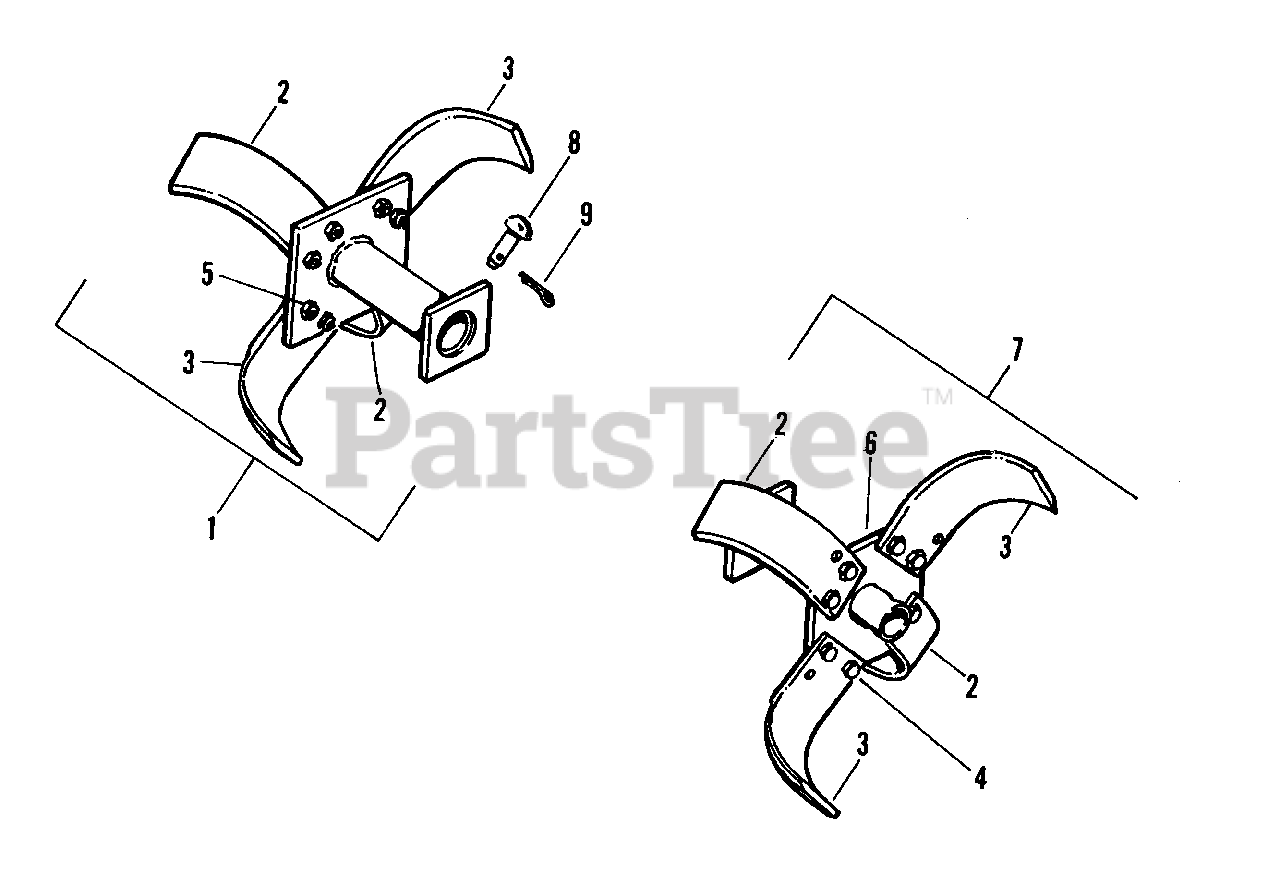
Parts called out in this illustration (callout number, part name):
1	TINE BLADE EXT. ASSY, L.H.
2	TINE, R.H.
3	TINE, L.H.
4	CAPSCREW, Hex, 3/8-16 x 1
5	NUT, Hex, Lock, 3/8-16
6	PLATE ASSY, Tine Extension
7	TINE BLADE EXT. ASSY, R.H.
8	PIN
9	CLIP, Spring
